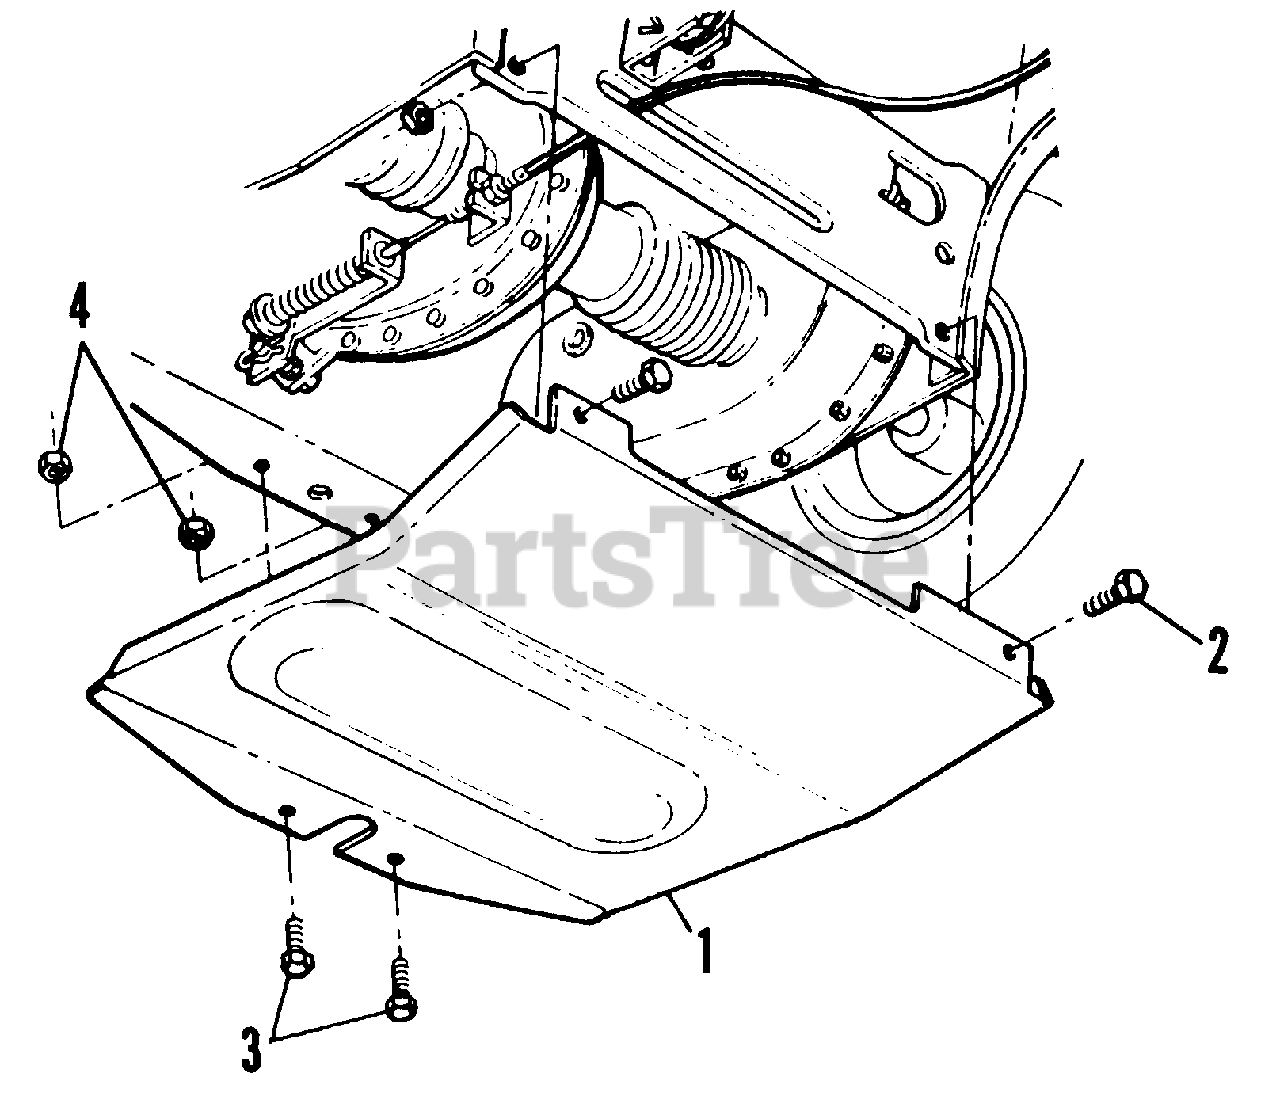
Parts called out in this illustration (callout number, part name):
1	SHIELD, Ice
2	SCREW, 5/16 - 18 x 5/8, Self-tapping
3	SCREW, 5/16 - 18 x 3/4 Hex Head Cap
4	LOCKNUT, 5/16 - 18 Hex Flange Top
